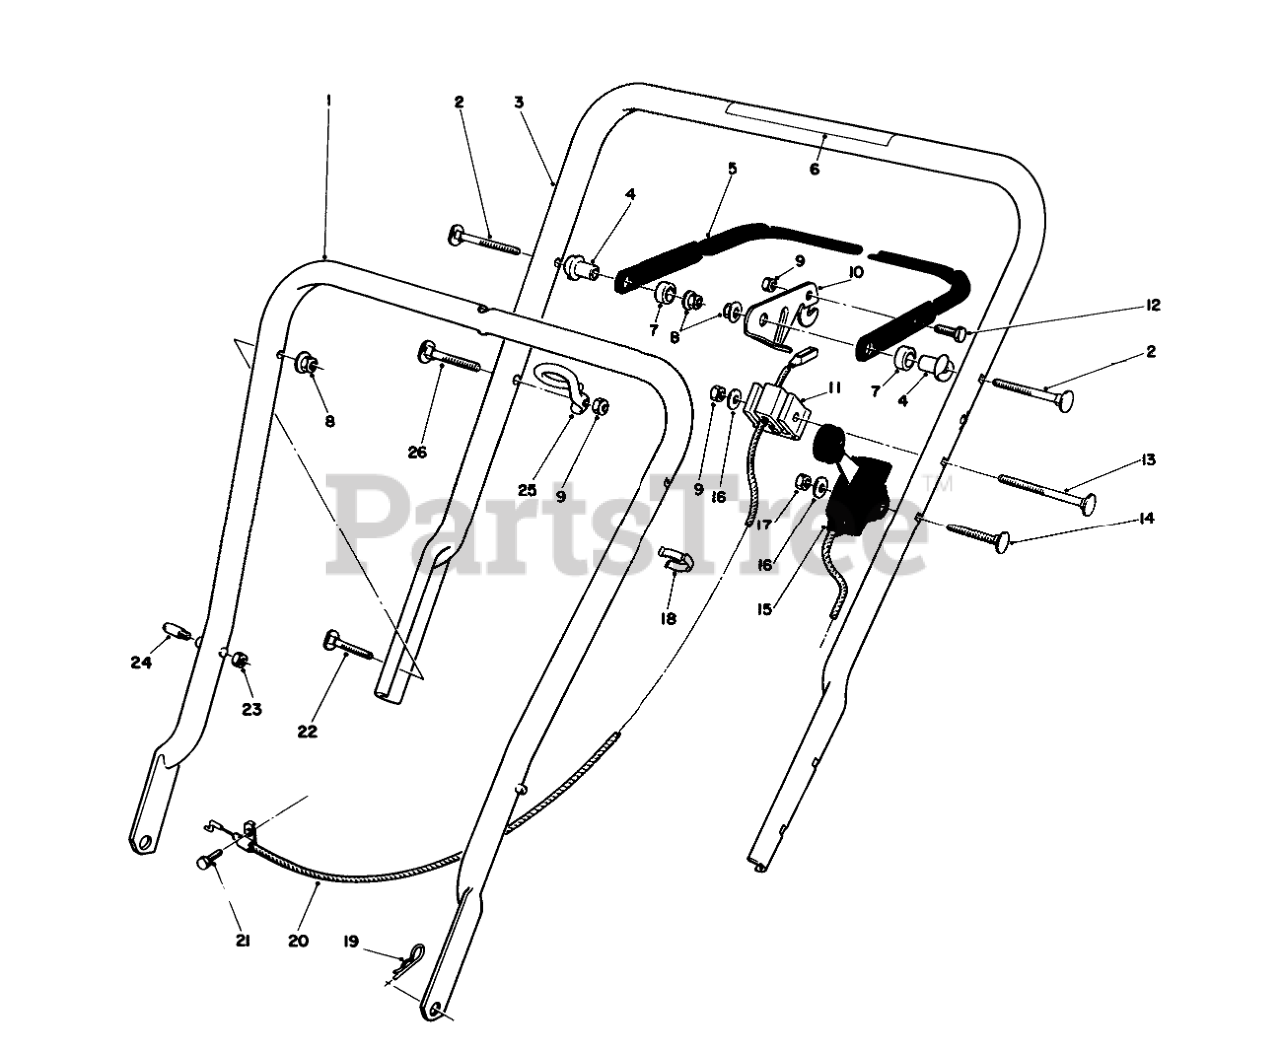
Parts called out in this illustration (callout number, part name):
1	LOWER HANDLE ASM
2	5/16-18 X 2 HNDLE SCREW
3	Handle-Upper(Incl. Ref. #6)
4	SPACER-SUPPORT
5	Bar-Control
6	Decal-Danger
7	SPACER-NYLON
8	NUT-LOCK, NI
9	NUT-LOCK, NI
10	LEVER-CONTROL
11	SUPPORT-CABLE
12	SCREW-HH
13	HANDLE SCREW
14	SCREW-HANDLE
15	THROTTLE CONTROL
16	WASHER-FLAT
17	NUT-LOCK, NI
18	BOWDEN CLIP
19	PIN-COTTER, HAIR
20	BRAKE CABLE
21	SCREW-HH
22	SCREW
23	NUT-LOCK, NI
24	HANDLE PIN
25	Guide
26	HANDLE SCREW
